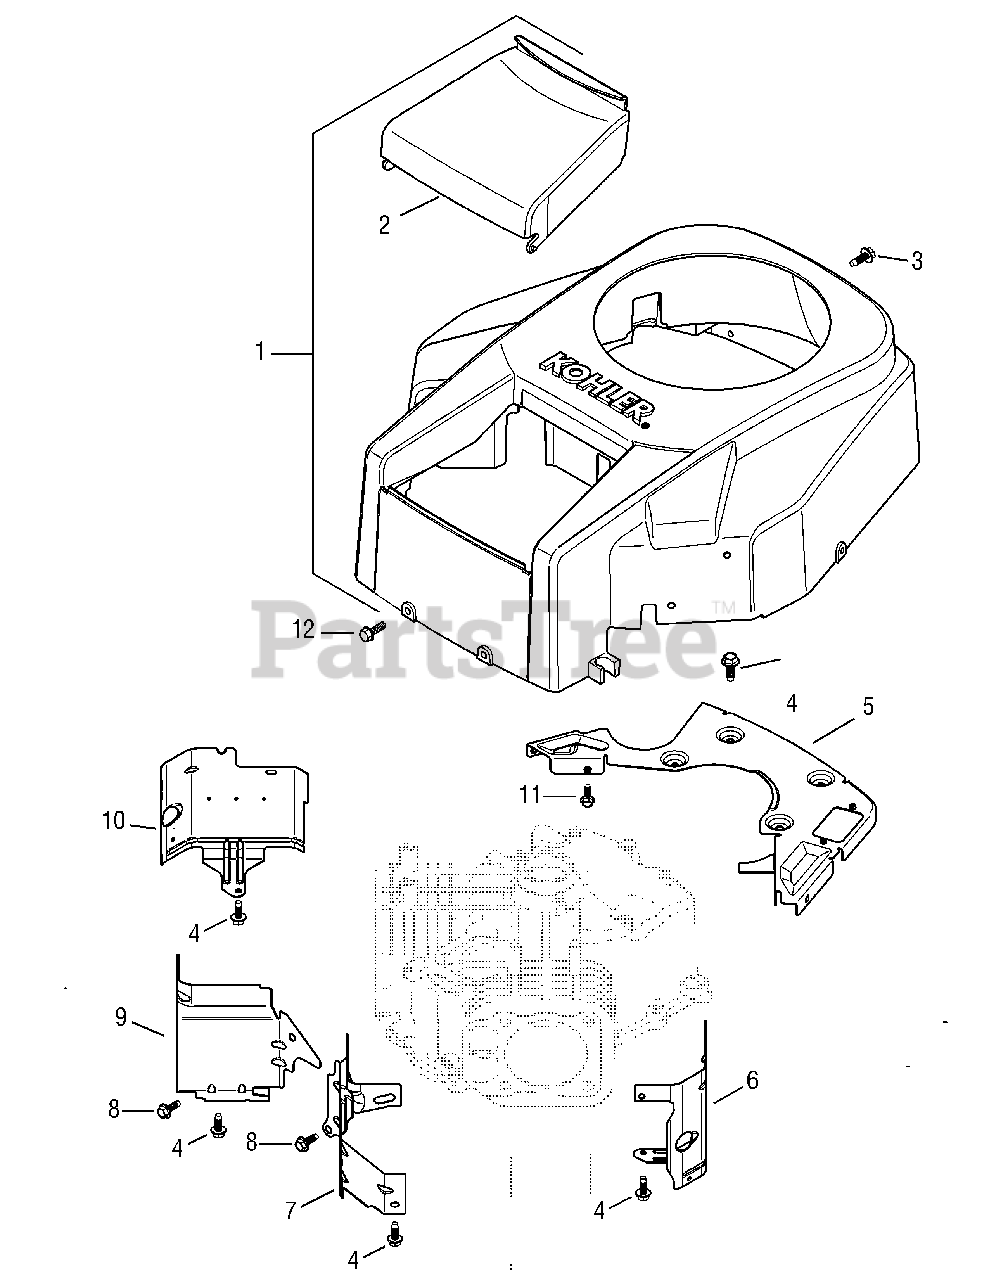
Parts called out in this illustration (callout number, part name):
1	Blower Housing (Inc. 2 & KH-41-037-10-S)
2	Air Cleaner Cover
3	Hex Flange Screw, M5 x 0.8 x 16
4	Hex Flange Screw, M6 x 1.0 x 16
5	Backing w/ Rectifier Plate - Regulator Opening
6	Cylinder Barrel Baffle - #2 Side
7	Valley Baffle - #2 Side
8	Hex Flange Screw, M5 x 0.8 x 10
9	Valley Baffle - #1 Side
10	Cylinder Barrel Baffle - #1 Side
11	Hex Flange Screw, M5 x 0.8 x 20
12	Hex Cap Screw, M6 x 1.7 x 18
